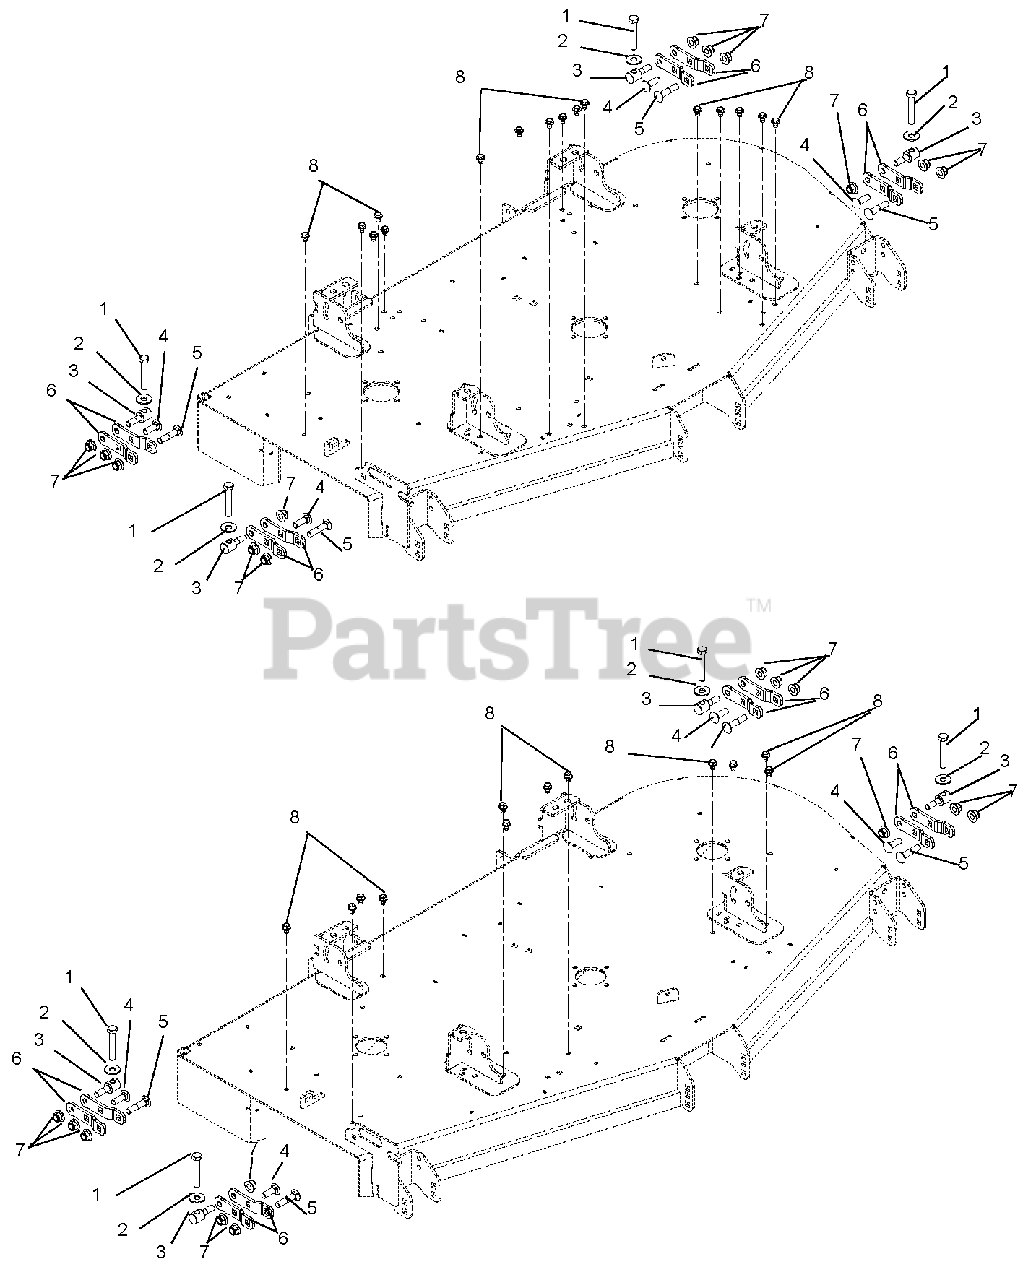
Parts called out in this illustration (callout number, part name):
1	Bolt, Hex .50-13 x 3.00 Grade 5 Full Thread
2	Washer-Flat-Steel .563 x 1.38 x .109
3	Trunnion, .50-13
4	Bolt-Round Head Square Neck .50-13 x 1.50 Grade 5
5	Bolt-Round Head Square Neck .50-13 x 2.25 Grade 5
6	Deck Leveling Bracket- Black
7	Nut-Locking-Nylon-Flange .50-13
8	Screw-Tapping .38-16 x .50 Hex Washer Head (185, 187)
